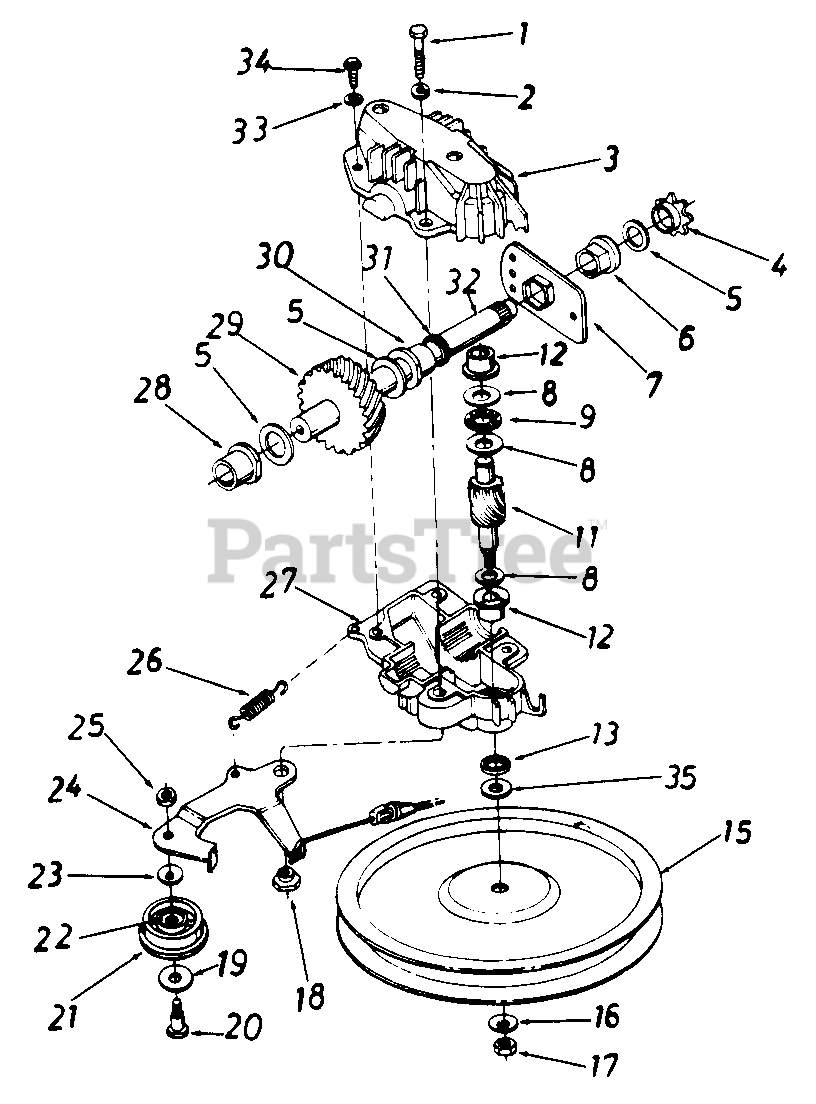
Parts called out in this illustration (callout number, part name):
1	Hex Patch Bolt 1/4-20 x 1.25"
2	L-Wash. 1/4" I.D.
3	Upper Hsg. Half
4	#48 Sprocket 7 T x 1/2 Pitch
5	Fl-Wash. 5/8" I.D. x .030
6	Hex Flange Brg. .631" I.D.
8	Thrust Wash. .382" I.D. x .70" O.D.
9	Thrust Bearing .375" I.D. x .812" O.D.
11	11 Tooth Pinion Shaft
12	Flange Bearing
15	Fl-Pulley 5.06" O.D.
16	Bell-Wash. .265" I.D. x .75"
17	Hex L-Nut 1/4-28 L.H. Thd.
18	Shld. Spacer .375" Dia. x .170
19	Fl-Wash. .390" I.D. x 1.0"
20	Shld. Bolt .375" Dia. x .40"
21	Fl-Idler Plastic 1.50" Dia.
22	Needle Brg. .375" x .31"
24	Idler Brk't. Ass'y.
25	Hex Patch L-Nut 1/4-28 Thd.
26	Extension Spring 1.12" Lg.
27	Lower Hsg. Half
28	Flange Bearing .566" Dia.
29	33 Tooth Helical Gear
30	Flange Bearing .629" Dia.
31	Oil Seal .625" Dia.
32	Gear Sprocket Shaft
33	L-Wash. #10 I.D.
34	Hex B-Tap Scr. #10 x .62
35	Hex Washer .26" x .88"
